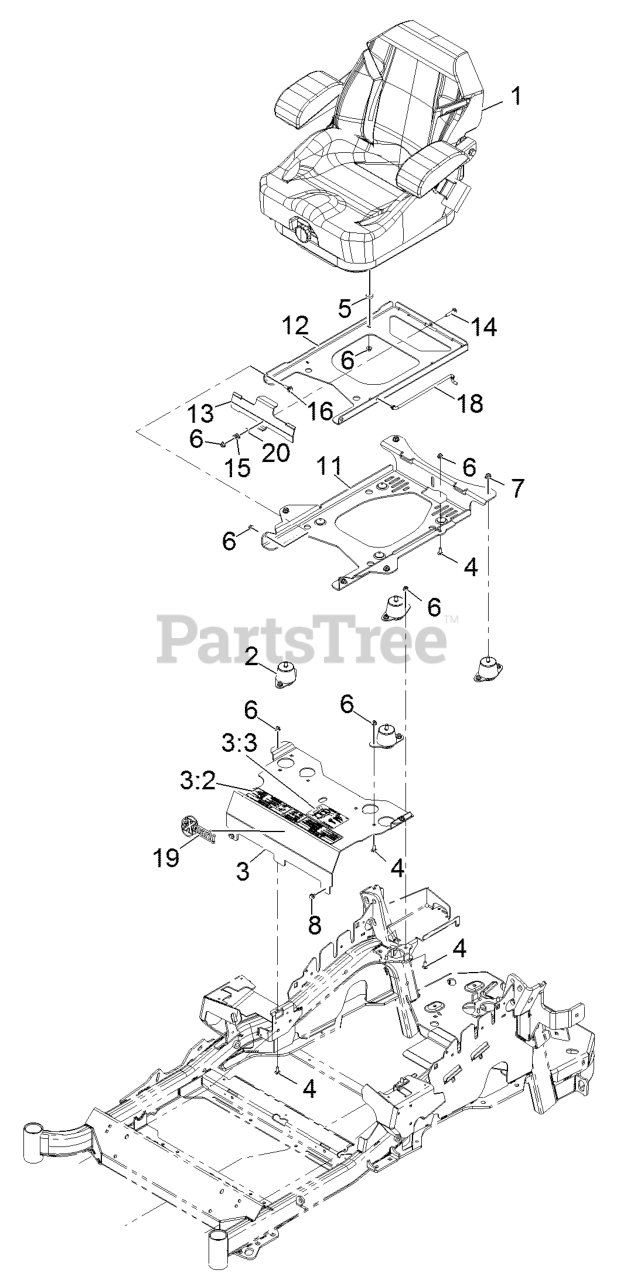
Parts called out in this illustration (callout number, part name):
2	ISOLATOR-SEAT
3	MOUNT-SEAT
3:2	DECAL-CONSOLE
3:3	DECAL-SERVICE AID
4	SCREW-CARR
6	NUT-HF, NI
7	NUT-HF, NI
11	PLATE-TILT, SEAT SUPPORT
12	PLATE-FRAME, SEAT
13	PLATE-LATCH, SEAT
14	BOLT-CARR
15	SPRING-COMPRESSION
16	SCREW-SHOULDER
18	ROD-PROP
20	WASHER-PLAIN
